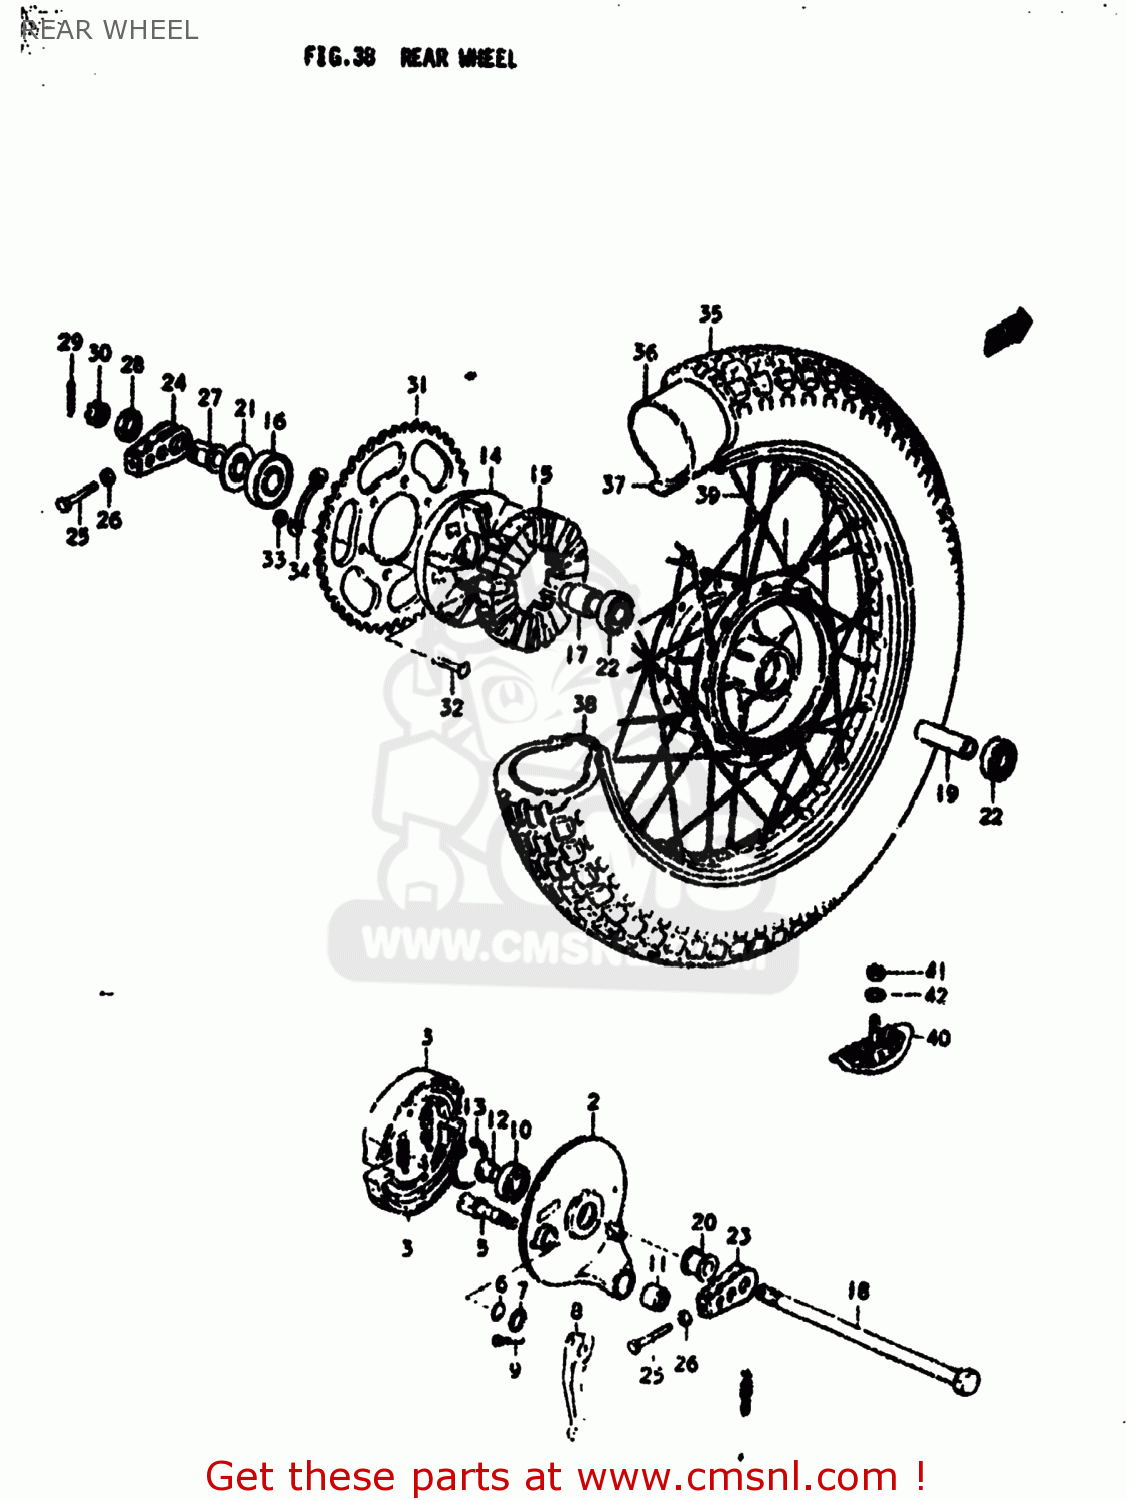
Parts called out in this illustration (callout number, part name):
1	DRUM,REAR HUB
2	PANEL,REAR HUB
3	SHOE,BRAKE (MCA)
4	SPRING
5	CAM,FRONT BRAKE
6	O-RING,BOSS
7	WASHER (15X24X1.6)
8	LEVER,REAR BRAKE CAM
9	BOLT
10	BALL BEARING
11	BUSH
12	SPACER,REAR HUB PANEL
13	CIRCLIP,42MM
14	DRUM,REAR SPROCKET MOUNT
15	CUSHION,REAR DRUM
16	BEARING
17	SPACER,REAR HUB BEARING
18	AXLE,REAR
19	SPACER (15.3X21.7X82)
20	SPACER,AXLE,RIGHT
21	SPACER,REAR AXLE,RIGHT
22	BEARING, RH
23	ADJUSTER,CHAIN
24	ADJUSTER,CHAIN
25	BOLT
26	NUT
27	SPACER,CHAIN ADJUSTER
28	NUT
29	PIN 30X40
30	NUT
31	SPROCKET,REAR
32	BOLT(8X33.5)
33	NUT
34	WASHER
35	TIRE
36	TUBE ASSEMBLY,WHEEL,INNER
37	PROTECTOR,WHEEL,INNER
38	RIM,REAR WHEEL
39	SPOKE SET,REAR
40	STOPPER,BEAD
41	NUT
42	WASHER
